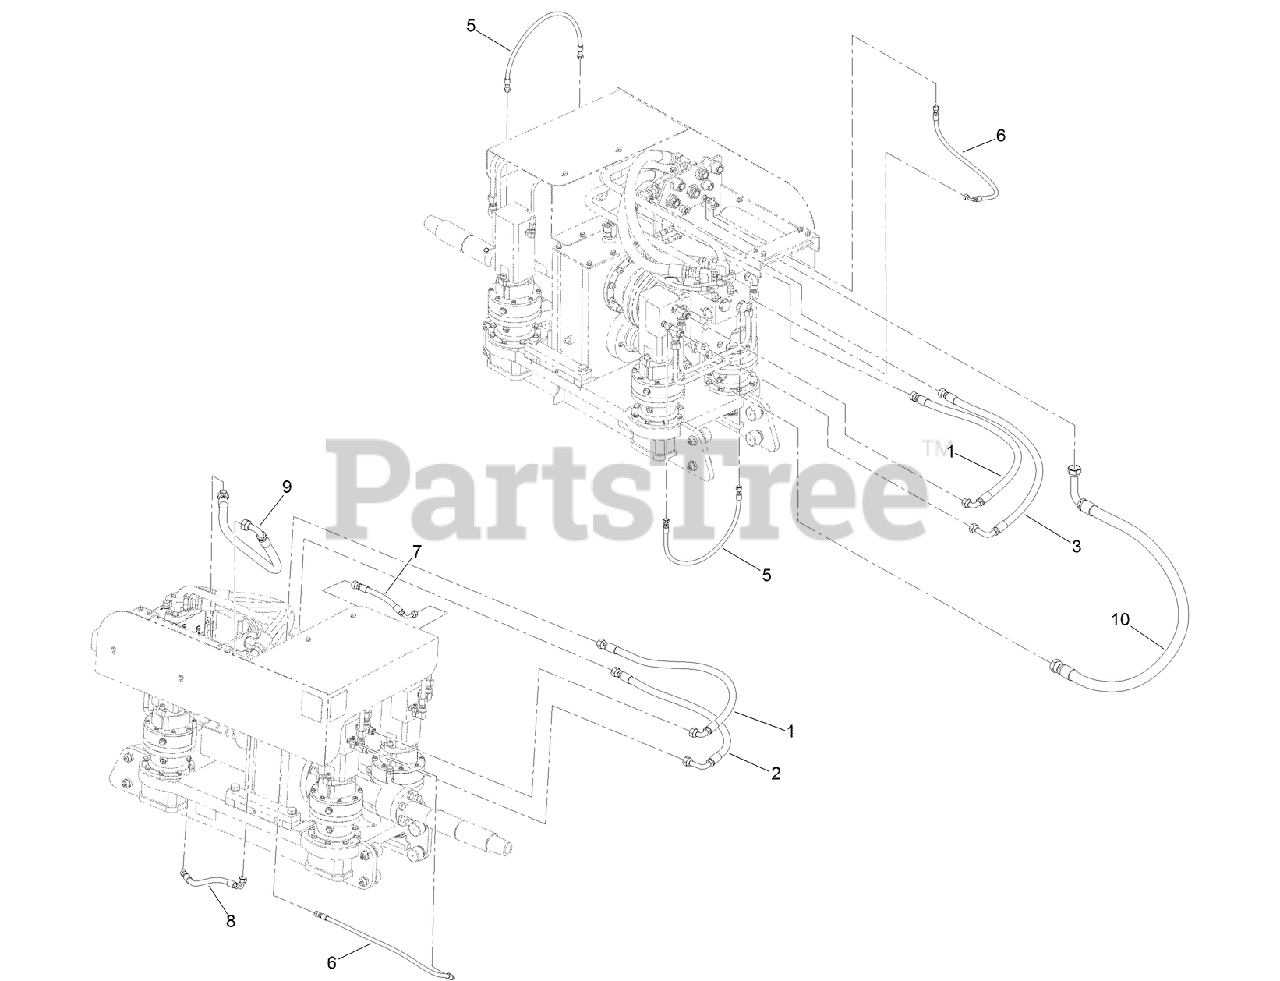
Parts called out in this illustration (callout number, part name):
1	HOSE ASM-HYD
2	HOSE ASM-HYD
3	HOSE ASM-HYD
5	HOSE ASM-HYD
6	HOSE ASM-HYD
7	HOSE ASM-HYD
8	HOSE ASM-HYD
9	HOSE ASM-HYD
10	HOSE ASM-HYD
